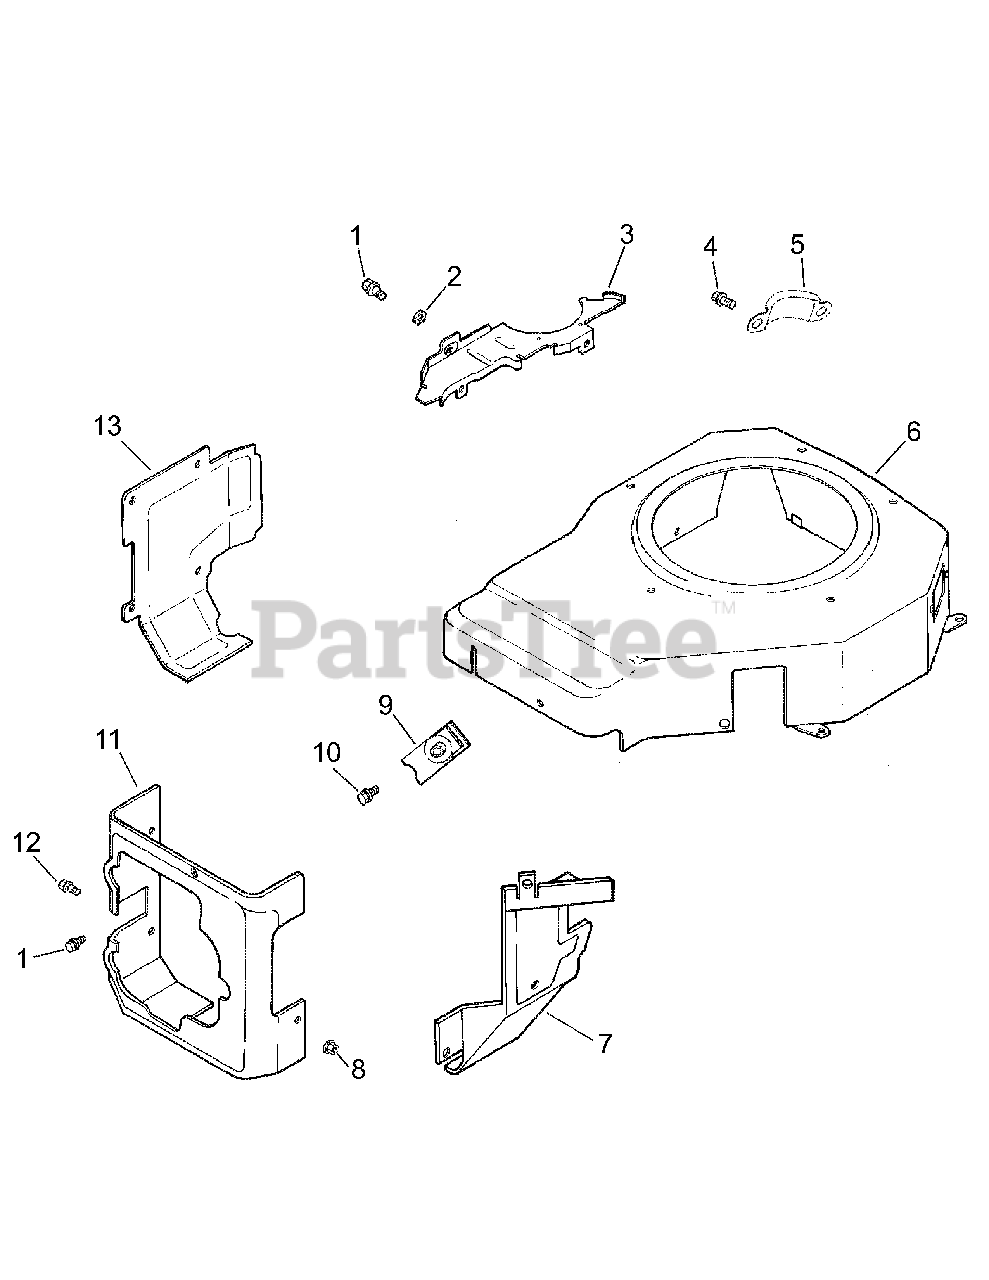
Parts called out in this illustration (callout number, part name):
1	Screw, Hex. Flange M5 x 0.8 x 10
2	Washer, Plain 1/4"
3	Plate, Blower Housing
4	Screw, Hex. Flange M5 x 0.8 x 10
5	Cover, Pinion
6	Housing, Blower
7	Baffle, Intake Side
8	Nut, Hex. Flange M5 x 0.8
9	Clip, Mounting
10	Screw, Hex. Flange M6 x 1.0 x 16
11	Baffle, Cylinder Head
12	Screw, Captive Washer M5 x 0.8 x 20
13	Baffle, Cylinder
